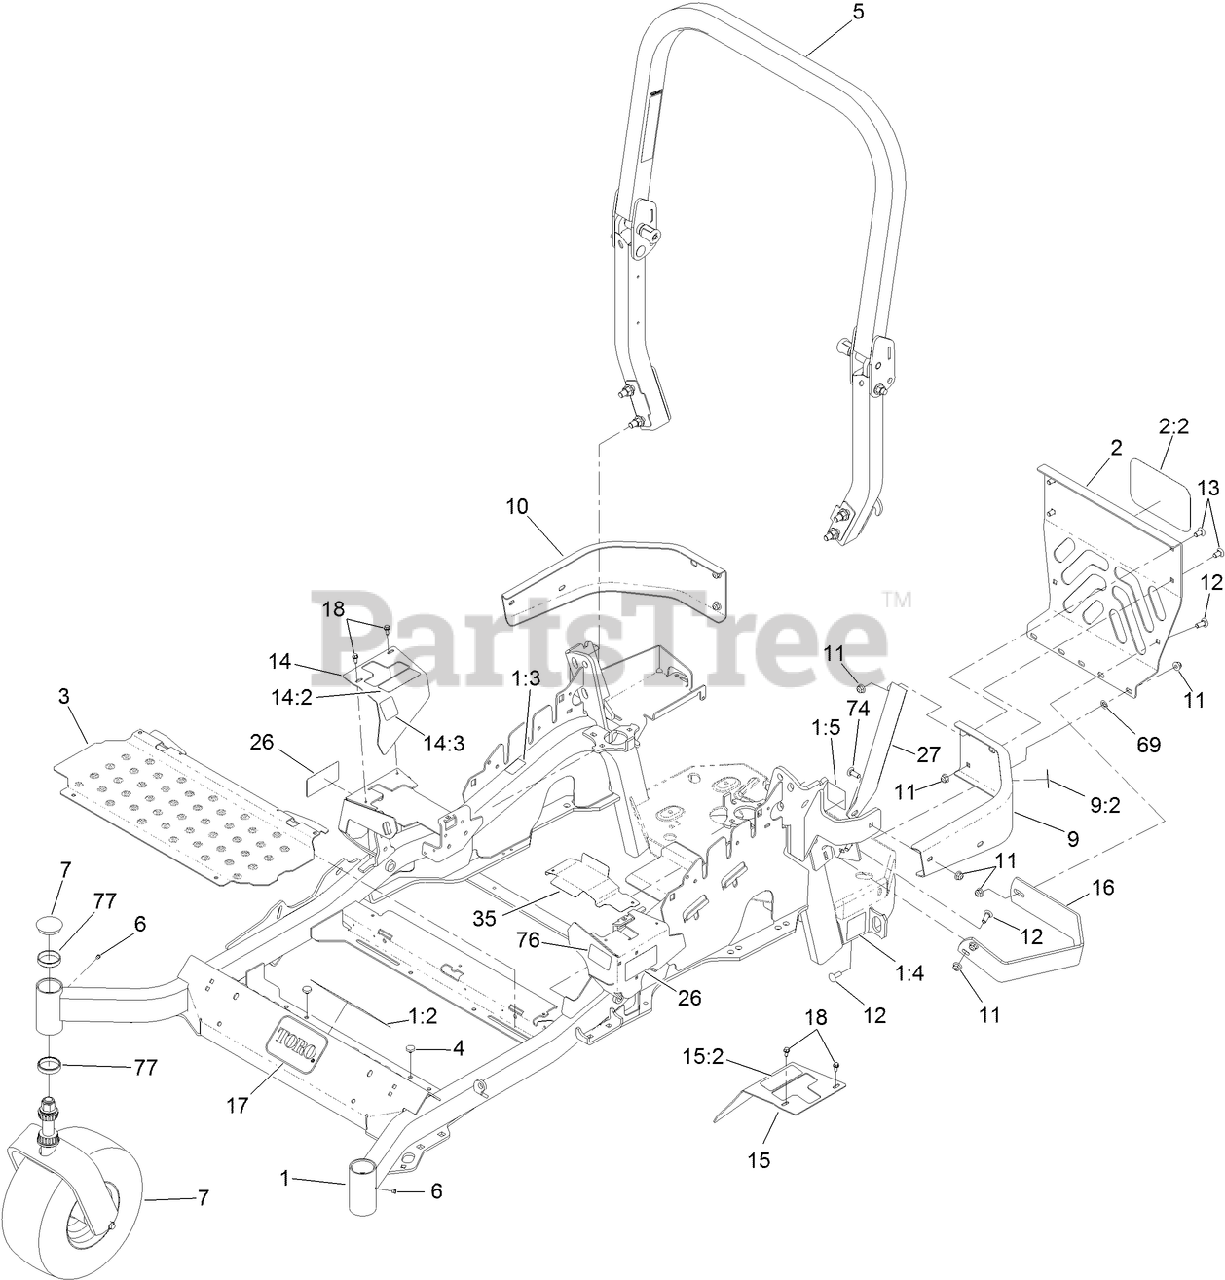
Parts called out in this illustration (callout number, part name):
1	MAINFRAME ASM
1:2	DECAL-DANGER SLOPE W/ROPS
1:3	DECAL-WARNING
1:4	DECAL-HAZARD, PINCHED FINGER
1:5	DECAL-SPARK ARRESTER
2	REAR GUARD ASM
2:2	DECAL
3	FLOORPAN
4	BUMPER
5	ROPS ASM
7	Caster Wheel ASM
9	LH BUMPER ASM
9:2	DECAL-WARNING
10	BUMPER-RH
11	NUT-HF, NI
12	SCREW-CARR
13	SCREW-CARR
14	RH MOTION CONTROL COVER ASM
14:2	DECAL-CONTROL, MOTION
14:3	DECAL-PARK BRAKE, CE
15	LH MOTION CONTROL COVER ASM
15:2	DECAL-CONTROL, MOTION
16	GUARD-MUFFLER
17	DECAL
18	SCREW-HWH
35	GUARD-BELT
69	NUT-PUSH
74	BOLT-CARR
76	DECAL-FUEL FILL, CE
77	CUP-BEARING
